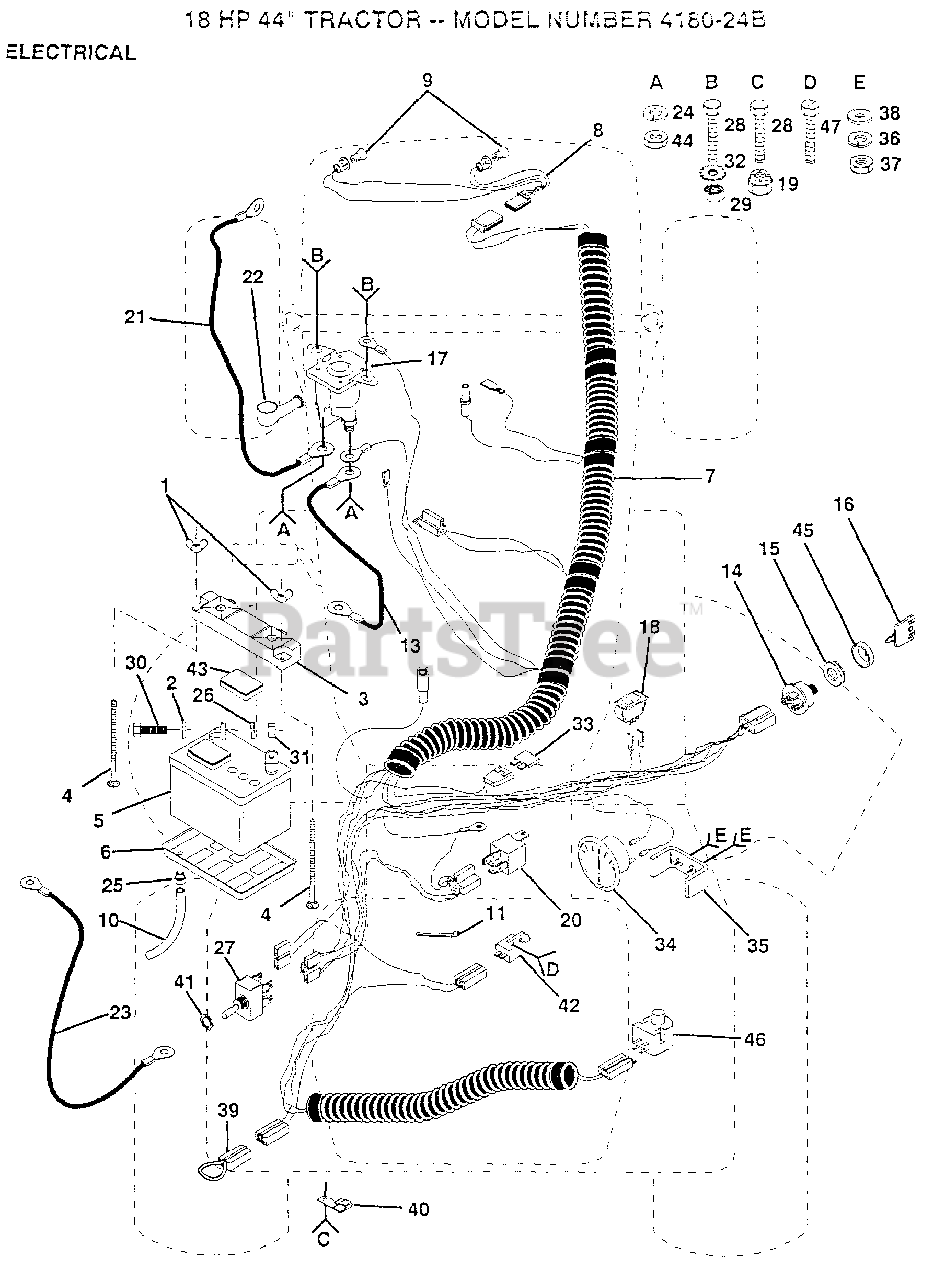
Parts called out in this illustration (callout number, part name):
2	WASHER
4	BOLT
6	"TRAY T, BATTERY"
7	IGNITION HARNESS
11	WIRE TIE
13	CABLE-BATTERY T
15	NUT IGNITION
16	KEY
18	SWITCH LT
20	RELAY ASSY T
21	"CABLE T, BATTERY"
23	CABLE T
25	HOSE CLAMP T
26	LOCKWASHER
28	BOLT
29	NUT
30	BOLT LT
33	FUSE HYT
34	AMMETER T
38	WASHER
40	CLIPT
41	HEX NUT T
42	SWITCH-INTER. GT
43	"CAP,BATTERY "
44	NUT
46	SWITCH SEAT
47	SCREW
